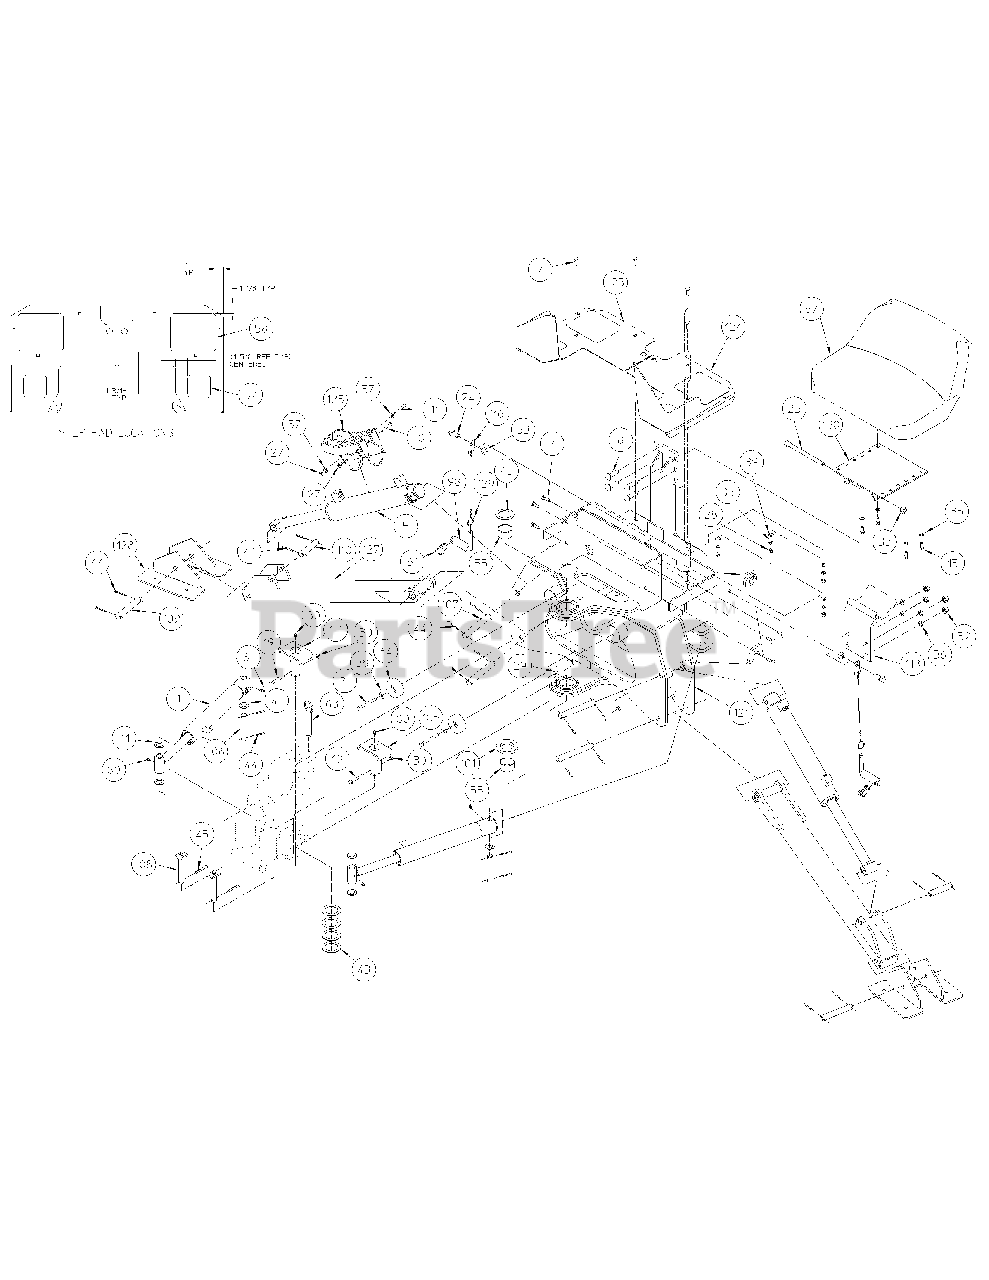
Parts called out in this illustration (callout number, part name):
1	HYDRAULIC CYLINDER, SWING
5	HYDRAULIC CYLINDER, STABILIZER
7	CARRIAGE BOLT, 5/16-18 X 1.00 GR 5
8	CARRIAGE BOLT, 1/2-13 X 1.75 GR 2
10	HEX HEAD CAP SCREW, 1/4-20 X 1.750 GR 5
11	HEX HEAD CAP SCREW, 1/4-20 X 2.0
13	HEX HEAD CAP SCREW, 5/16-18 X .75 GR 5
19	HEX HEAD CAP SCREW 5/16-24 X 2.250 GR 5
21	HEX HEAD CAP SCREW, 5/16-18 X 3.0 GR 5
24	HEX HEAD CAP SCREW, 1/2-20 X 1.0 GR 5 SAE
25	HEX HEAD CAP SCREW, 1/2-20 X 6.50 GR 5
27	NUT, HEX 1/4-20 GR 5 LOCK
28	NUT, HEX 5/16-18 GR 5
29	NUT, HEX 5/16-18 GR 5 LOCK
30	NUT, HEX 5/16-24 LOCK
32	NUT, HEX 1/2-13 GR 5
33	NUT, HEX 1/2-20 GR 5 LOCK
35	LOCK WASHER, 5/16
36	LOCK WASHER, 1/2
37	FLAT WASHER, 1/4 SAE
38	FLAT WASHER, 5/16
39	FLAT WASHER, 5/16 SAE
41	MACHINE BUSHING, 1-1/4 X 3/4 X 14GA
43	MACHINE BUSHING, 2-1/2 X 1-3/4 X 14GA
44	COTTER PIN, HARD 3/16 X 1.25
45	COTTER PIN, 1/4 X 1-1/2
55	PRE LUBRICATED BEARING
57	STEP PAD SURFACING 3X3
58	STEP PAD SURFACING 5X6
63	FASPIN, 3/4 DIA X 3
64	RUBBER BUMPER
67	SEAT, BACKHOE
76	CABLE ASSEMBLY
80	GREASE FITTING, 1/4-28, STRT
81	GREASE FITTING, 1/4-28, 45 DEG
99	SPACER, LONG
101	THRUST WASHER
105	PIVOT PIN WELDMENT
106	PIVOT PIN, 3/4" DIA X 4-1/16
107	PIVOT PIN, 3/4" DIA X 5-5/8
108	SWING CYL PIN WELDMENT
109	PIVOT PIN, STAB PAD
110	PIVOT PIN, STAB CYL ROD
111	UPPER PIVOT PIN WELDMENT
113	SEAT BRACKET WELDMENT
121	MAINFRAME WELDMENT
123	RH FLOOR WELDMENT
124	LH FLOOR WELDMENT
125	STEP WELDMENT
127	STABILIZER LEG WELDMENT
128	STABILIZER PAD WELDMENT
129	RING LOCKING
130	SEAT PLATE WELDMENT
